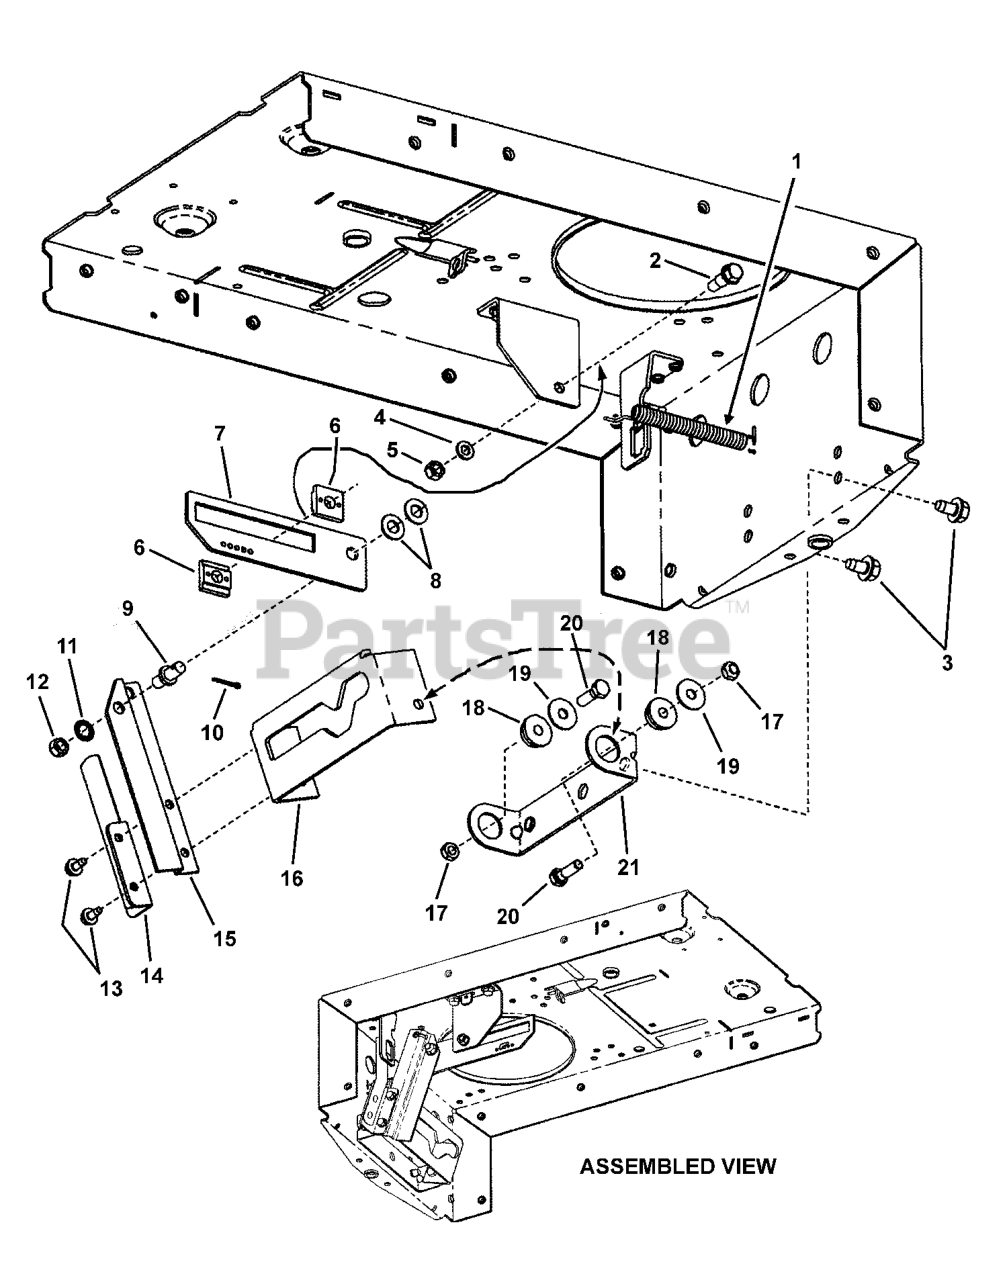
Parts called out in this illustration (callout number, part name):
1	SPRING, Clutch & Brake
2	BOLT, 5/16-18 Shoulder
3	SCREW, 3/8-16 x 5/8" Hex Washer Self-Tap
4	WASHER, 5/16" Split Lock
5	NUT, 5/16-18 Hex, GR 5 or B
6	SLIDE HALF
7	BRACKET, Slide
8	WASHER, 3/8" Flat SAE
9	STUD, Clutch Link (3/8-24 thread)
10	PIN, 3/32 x 3/4" Cotter
11	WASHER, 3/8" Internal Tooth Lock
12	NUT, 3/8-24 Hex, GR 5 or B
13	SCREW, 1/4-20 x 1/2" Hex Washer Self-Tap
14	ASSEMBLY, Leaf Spring
15	ARM, Yoke
16	LIFT, Yoke
17	NUT, 5/16-24 Hex Center Lock
18	BEARING, Yoke
19	FENDER WASHER, 5/16"
20	SCREW, 5/16-24 x 1" Hex Head Cap, GR 5
21	COLLAR, Yoke
